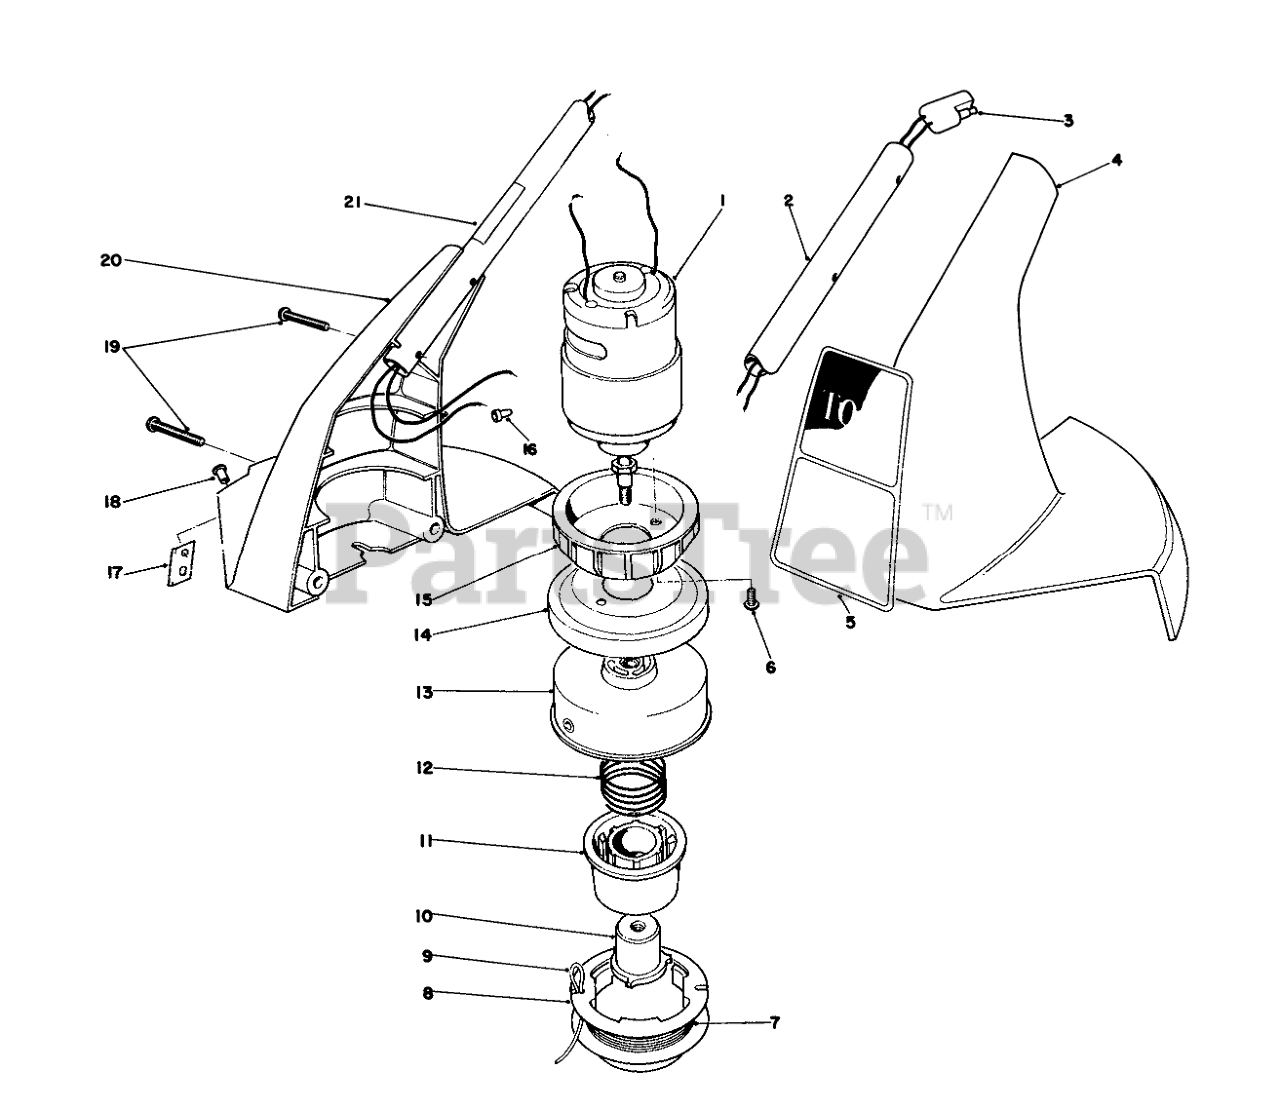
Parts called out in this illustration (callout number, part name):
1	MOTOR ASM
2	EXTENSION HANDLE
3	WIRING HARNESS LOWER
4	Housing-L.H.
5	Decal-CL-710
6	SCREW
7	Prewound Spool
8	CAP-SPOOL
9	Line-Cutting (30- .05 Dia.)
10	DRIVER
11	CORE - SPOOL
12	Spring
13	Drum w/Eyelet
14	DRUM CUP
15	Casting-Heat Sink
16	Connector
17	Knife Blade
18	Rivet
19	SCREW-PLASTITE
20	R.H. Motor Housing (Incl. Ref. #17 & 18)
21	REP. SERIAL PLT
